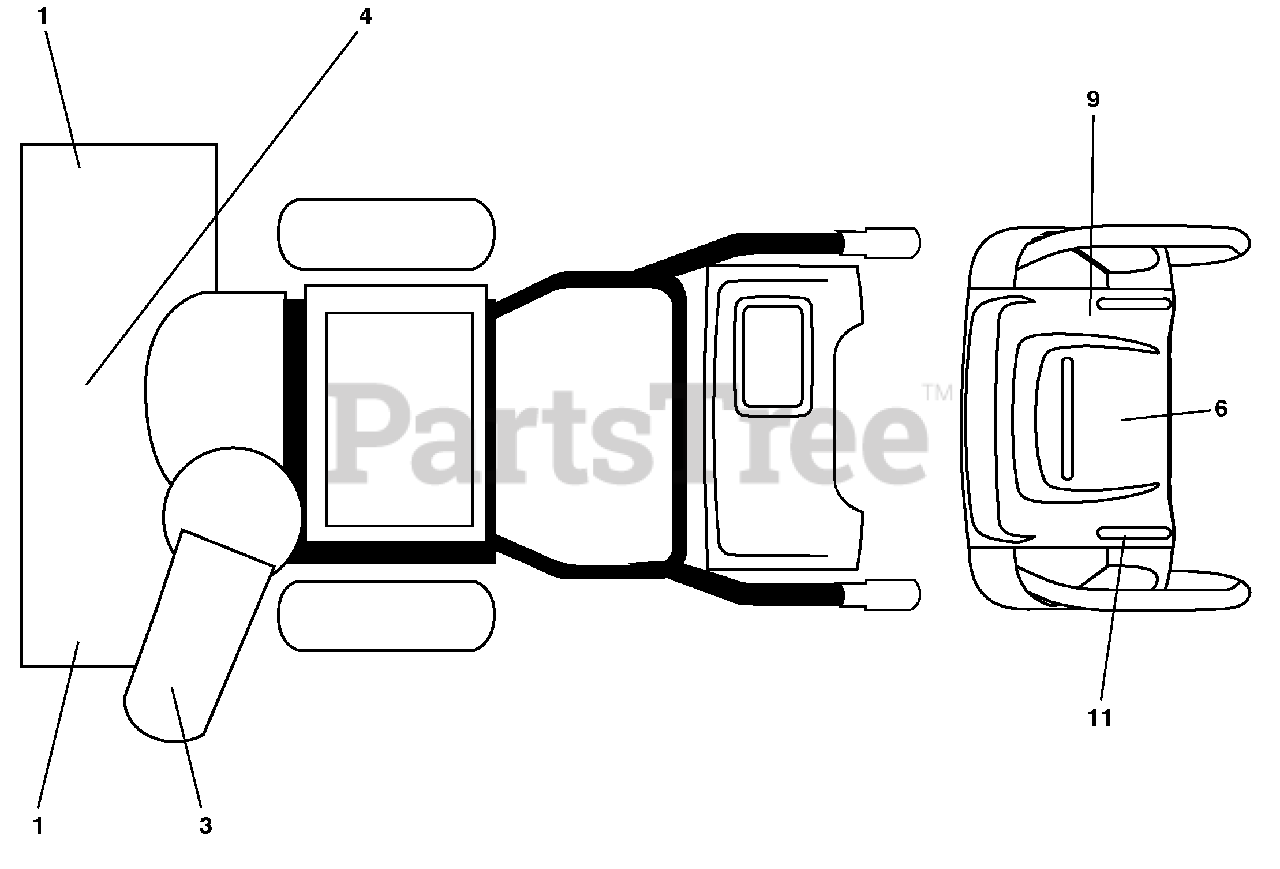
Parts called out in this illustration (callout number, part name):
1	DECAL, DANGER
3	DECAL, DANGER, DEFLECTOR
4	DECAL, DANGER
6	DECAL, INSTRUCTION
9	DECAL, CON RT SPD/LEV/PWST
11	DECAL, CON LT WD/DEF
11	OWNER'S MANUAL, ENGLISH
11	OWNER'S MANUAL, FRENCH
